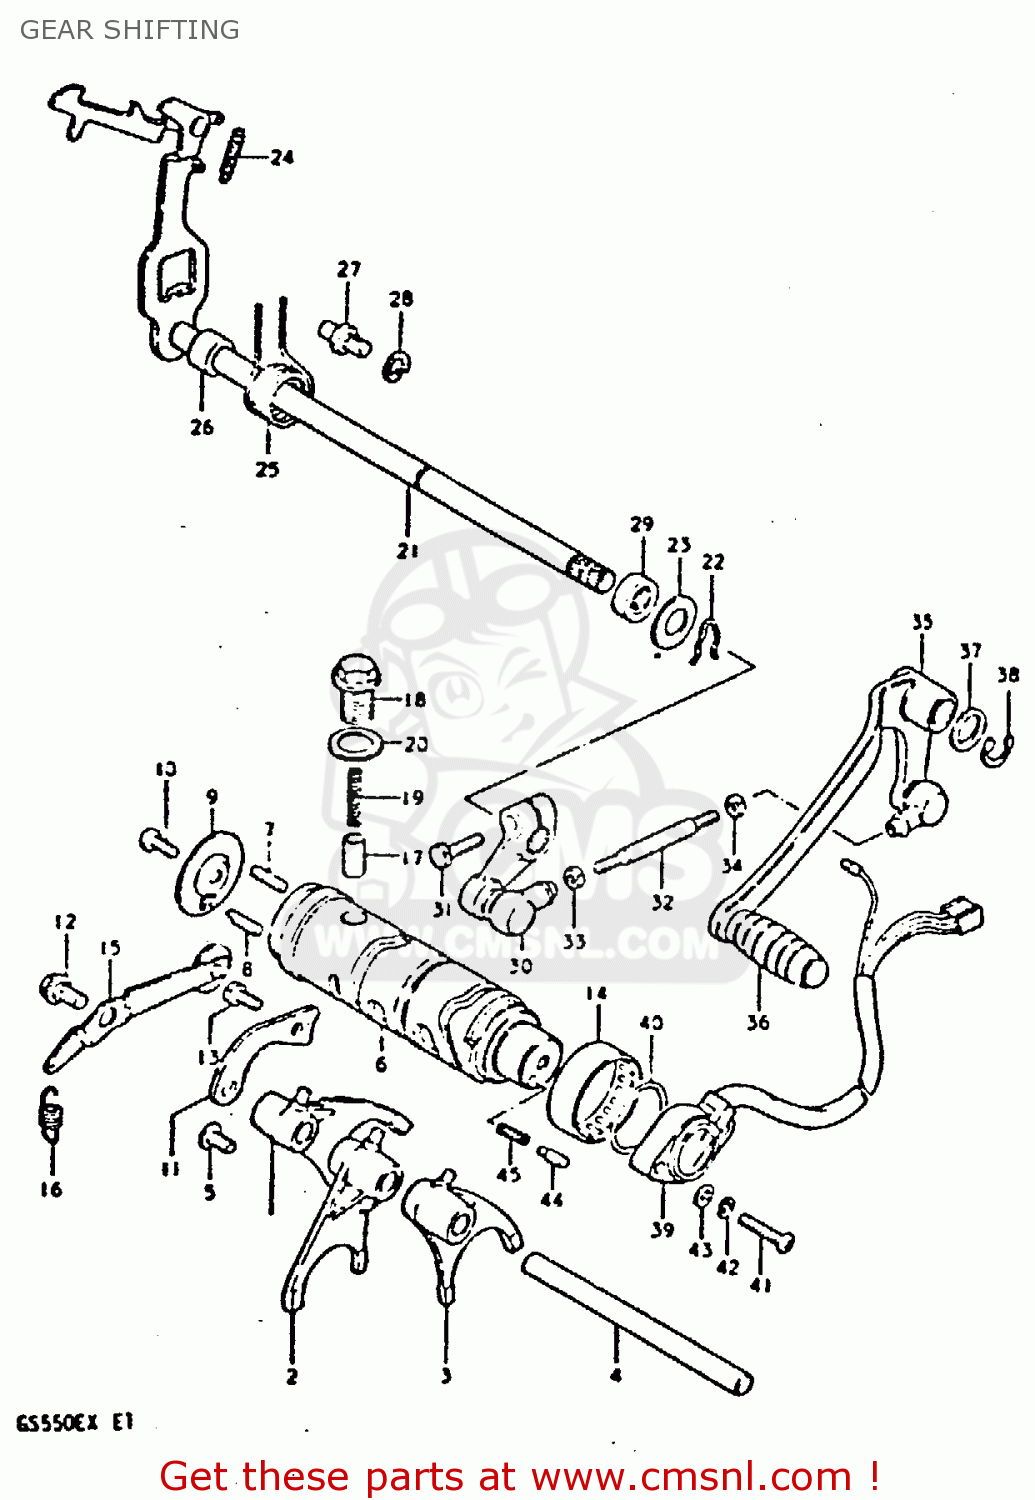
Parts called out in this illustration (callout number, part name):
1	FORK,GEAR SHIFT NO.1
2	FORK,GEAR SHIFT NO.2
3	FORK,GEAR SHIFT NO.2
4	SHAFT,GEAR SHIFT FORK
5	SCREW
6	CAM,GEAR SHIFT
7	PIN(4X18.5)
8	PIN
9	RETAINER,GEAR SHIFT CAM DR PIN
10	SCREW
11	GUIDE,GEAR SHIFTING CABLE
12	BOLT
13	BOLT
14	BEARING(40X47X12)
15	STOPPER,GEAR SHIFT CAM NO.1
16	SPRING
17	STOPPER,GEAR SHIFT CAM NO.2
18	HOLDER,GEAR SHIFT CAM STOP SPR
19	SPRING
20	GASKET(14X19.2X2) (NAS)
21	SHAFT,GEAR SHIFT
22	SPRING,RETAINER
23	WASHER (12.5X27X1.6)
24	SPRING
25	SPRING
26	SPACER(12X20X15.3)
27	STOPPER,GEAR SHIFT CAM
28	WASHER
29	OIL SEAL
30	ARM,GEAR SHIFT LINK
31	BOLT
32	ROD,GEAR SHIFT LINK
33	NUT
34	NUT
35	LEVER ASSEMBLY,GEAR SHIFTING
36	RUBBER,GEAR SHIFT PEDAL
37	WASHER(12.5X20X1)
38	CIRCLIP
39	TERMINAL BASE ASSY,GEAR SHIFT
40	O-RING (D:2.4 ID:26.2)
41	SCREW 5X20
42	LOCK WASHER
43	WASHER
44	PIN(5X15.5)
45	SPRING
